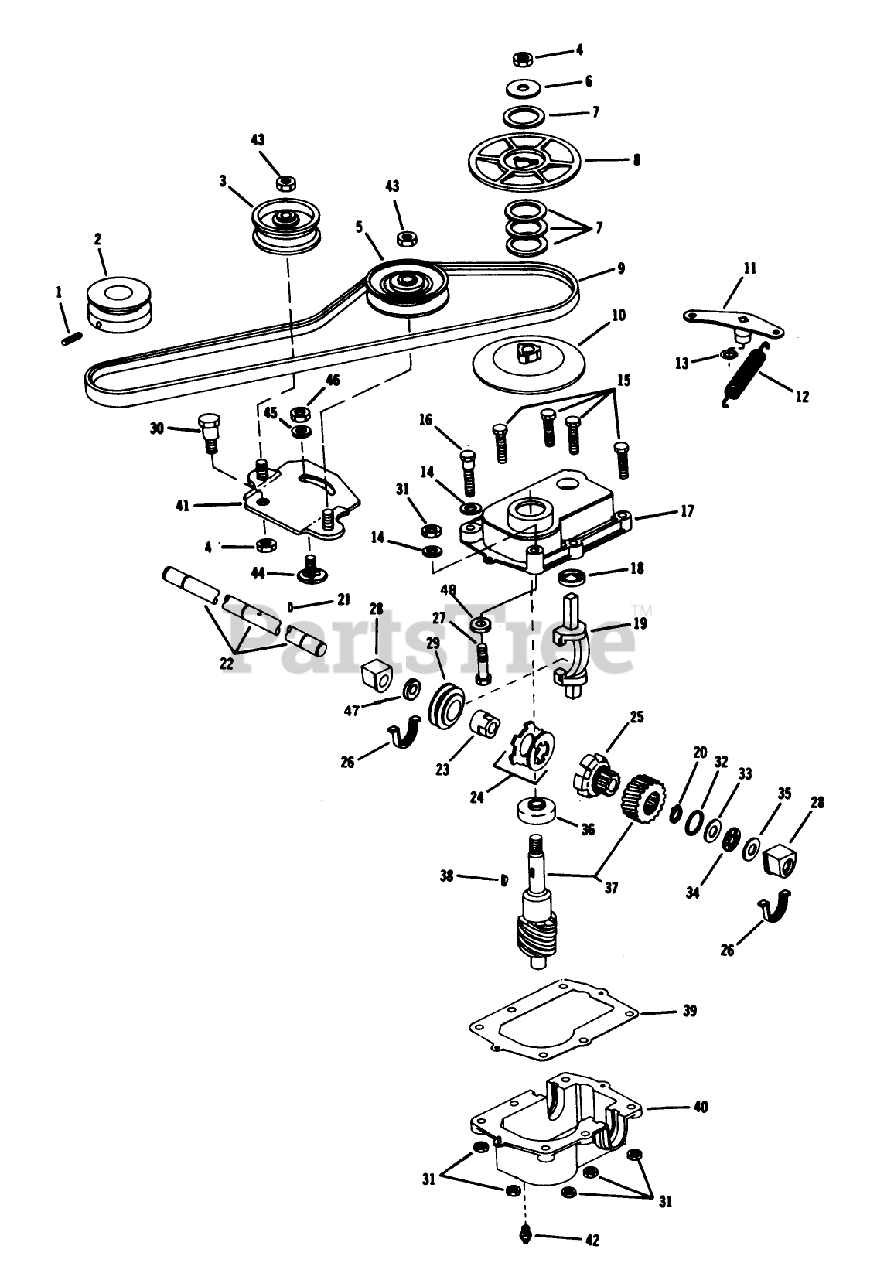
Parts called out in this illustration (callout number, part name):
1	SET SCREW F
2	PULLEY F
3	PULLEY NEWHAM IND *B
4	LOCKNUT
5	IDLER NEW HAM IND
6	WASHER
8	PULLEY UPPER PL
9	V-BELT
10	PULLEY LOWER PL
12	SPRING
13	O-RING
18	GUIDE ELCO
20	RET RING
21	PIN DRIVE LOCK
25	DRIVER BROCKWAY
28	BEARING & SEAL AY (12)
31	LOCKNUT E
33	WASHER-THRUST
35	THRUST WASHER
36	BEARING-BALL
38	KEY GALGER
39	GASKET HOOSIER
42	FITTING LINCOLN
43	NUT-JAM, LOCKING
45	WASHER M
46	NUT-LOCK F
47	WASHER
